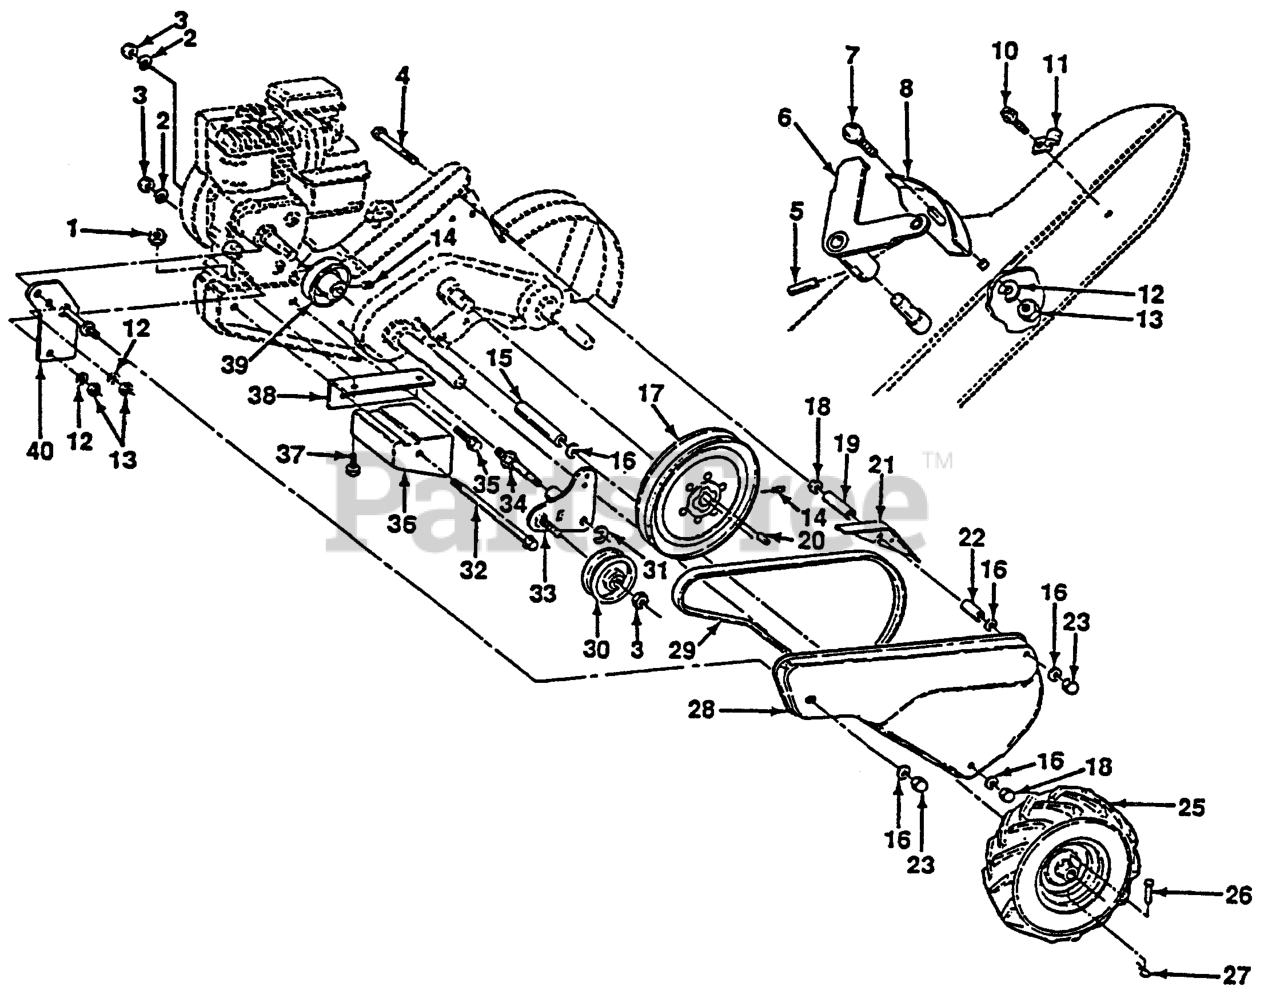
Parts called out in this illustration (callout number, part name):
1	NUT
2	WASHER, LOCK 3/8
3	NUT.HEX.3/8-16UNC
4	Bolt, Hex 5/16-18 x 4-3/4
5	DRIVE PIN
6	LEVER ASM CRT
8	PANEL.INDICATOR.SHIFT.BLACK
10	TAPPING SCREW
11	CONDUIT.CLIP.PLATED
12	LOCKWASHER
13	NUT
16	WASHER
17	SHEAVE 10" CRT
18	NUT
19	SPACER CRT
22	SPACER CRT
25	TIRE.13X5-6.CHEVRON.TILLER
25	RIM ASM.6"WHITE.TILLER
25	VALVE STEM LT
26	RIVET,DRILLED
27	RETAINER M
29	V-BELT CRT
30	PULLEY-IDLER TI
32	BOLT.FIN.HEX.3/8-16UNC
33	BRACKET ASSY TI
34	SHIFT ARM CRT
35	BOLT
36	COUNTERWEIGHT.LH.CRT
37	BOLT
38	BRACKET LH CRT
39	SHEAVE ENGINE CRT
40	BRACKET ASSY CRT
